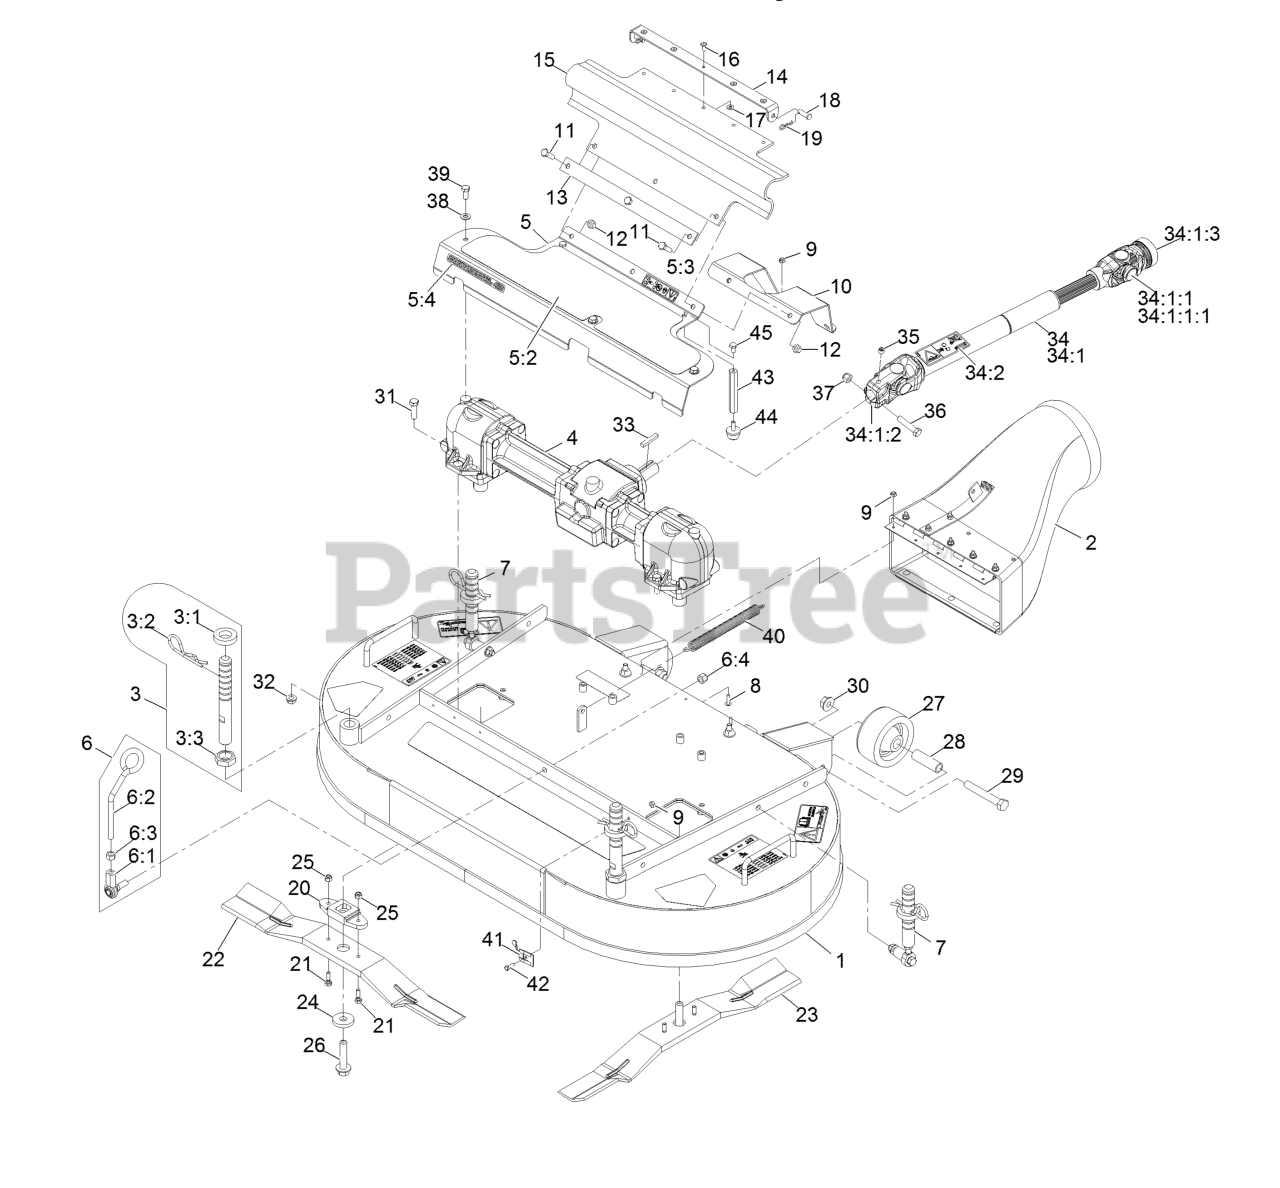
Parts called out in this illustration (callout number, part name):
1	Deck ASM
2	Discharge Tube ASM
3	Front Deck Height Adjust ASM
3:1	Spacer-Deck Support
3:2	Pin-Cut Height
3:3	Nut-Jam 7/8-9
4	Gearbox ASM
5	Asm, Gearbox Cover W/Decal (42")
5:2	Pad-Anti Skid
5:3	Decal-Danger
5:4	Decal-Commercial 42
6	Deck Latch ASM
6:1	Balljoint
6:2	Latch-Deck
6:3	Nut-Hex 3/8-24
6:4	Nut-Nyloc 3/8-24
7	Rear Deck Height Adjust ASM
8	Screw-Truss Head #10-24 X 3/4
9	Nut-Nyloc #10-24
10	Guard-Drive Shaft
11	Screw-HH 5/16-18 X 1
12	Nut-Nyloc 5/16-18
13	Strap-Drive, Line Cover
14	Bracket-Guard, PTO
15	Guard-PTO
17	Washer-#10 Std
18	Pin-Clevis 5/16 X 1 49/64
19	Hairpin-Cotter
20	Driver-Blade
21	Bolt-Shear 1/4-20 X 7/8
22	Blade, RH (42") Red
23	Blade, LH (42") Black
25	Nut-Nyloc 1/4-20
26	Bolt-Blade 1/2-20 X 2 1/4
27	Roller-Deck
28	Spacer-Roller
29	Screw-HH 1/2-13 X 3 1/2
30	Nut-Whizlock 1/2-13
31	Screw-HH 3/8-16 X 1 1/4
32	Nut-Whizlock 3/8-16
33	Key-Machine 1/4 X 1/4 X 1 1/2
34	Drive Shaft ASM
34:1	Drive Shaft-Telescoping
34:1:1	U-Joint Kit
34:1:1:1	Fitting-Grease
34:1:2	Yoke-Keyed
34:1:3	Yoke-Quick Disconnect
34:2	Decal-Danger, Driveline
35	Setscrew-3/8-16 X 3/8
36	Screw-HH 3/8-16 X 1 3/4
37	Nut-Nyloc 3/8-16
38	Washer-5/16 SAE
39	Screw-HH 5/16-18 X 3/4
40	Spring-Extension
41	Clip-Deck, Hold Up Rod
42	Screw-HH Machine 10-24 X 5/8
43	Stand-Off
45	Screw-HH 1/4-20 X 1/2
